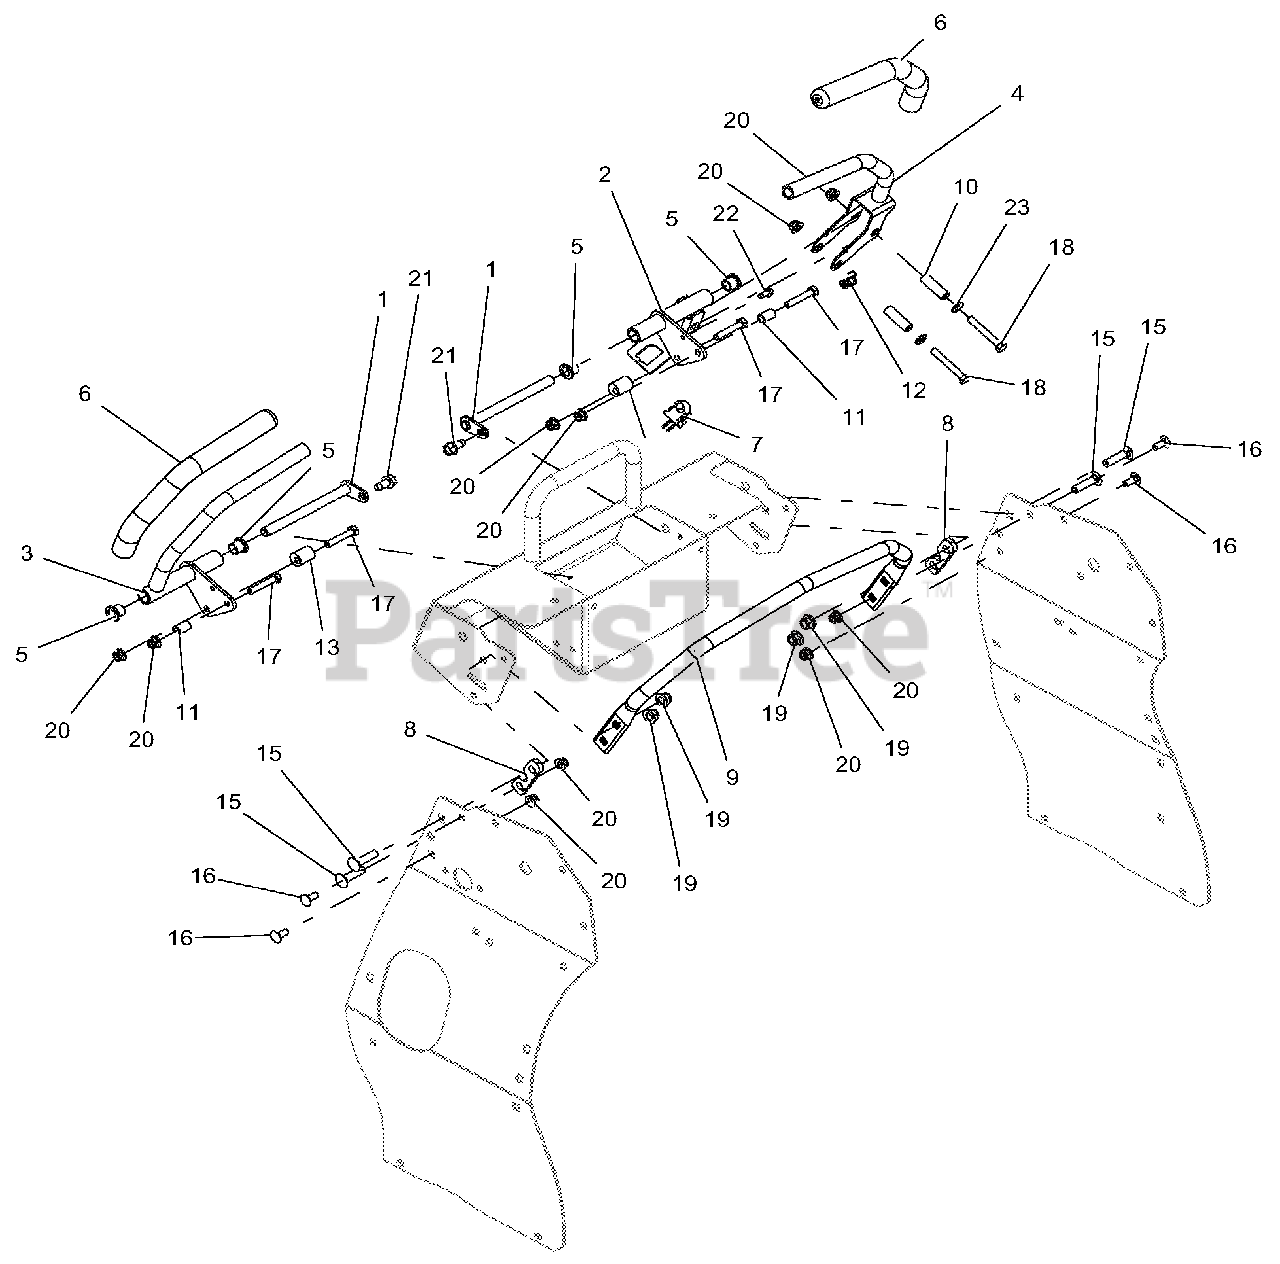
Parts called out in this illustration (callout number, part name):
1	W LDMT, PIN & LOCK
2	W LDMT, CONTROL MOUNT (LH)-BLACK
3	W LDMT, CONTROL ARM (RH)
4	CONTROL, ARM , L H
5	BRG, FLG .500 X .620 X .500 BRNZ
6	GRIP, HANDLEBAR REV
7	SWITCH, SEAT OVERIDE (N.O. )
8	SHIM, BAR 5 DEG SPEED-BLACK
9	STOP, FORWARD STEERING
10	BSHG, SLV .33X.50X1.56
11	BSHG-SLV .328X.50X.75
12	SPRG, EXTENSION
13	ECCENTRIC
15	BLT-RDHDSQNK .38-16X1.50 G5 Y
16	BLT-RDHDSQNK .31-18X.75 G5 YWZC
17	BLT-HEX .31-18X1.75 GR5 YWZC
18	BLT-HEX .31-18X2.25 GR5 YWZC
19	NUT-LK-NYL-FLG .38-16 YWZ C
20	NUT-LK-NYL-FLG .31-18 YWZC
21	SCR-TAP .38-16X.75 HWH TR YW Z
22	SCR-TAP .25-20X.50 HWH TR YW Z
23	W SHR-FL-STL.344X.688X.065YWZC
